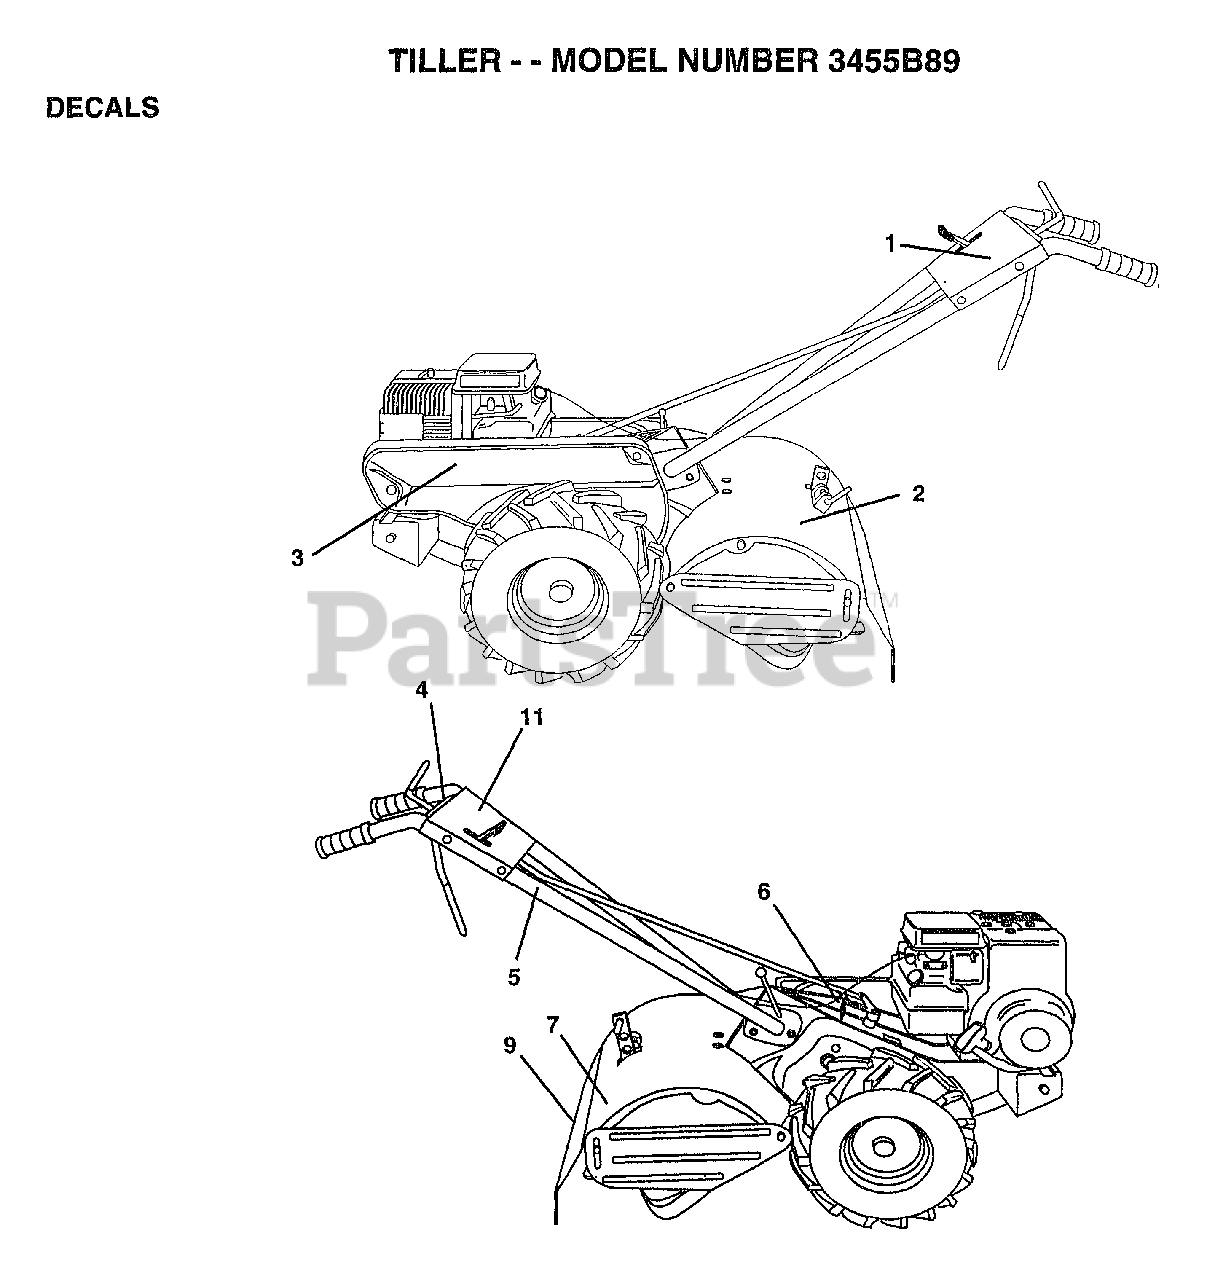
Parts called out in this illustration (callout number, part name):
3	DECAL.GUARD.BLT.W
5	DECAL TI
6	DECAL CRT
7	DECAL.TINE.SHIELD
9	DECAL TI
11	DECAL REVERSE
